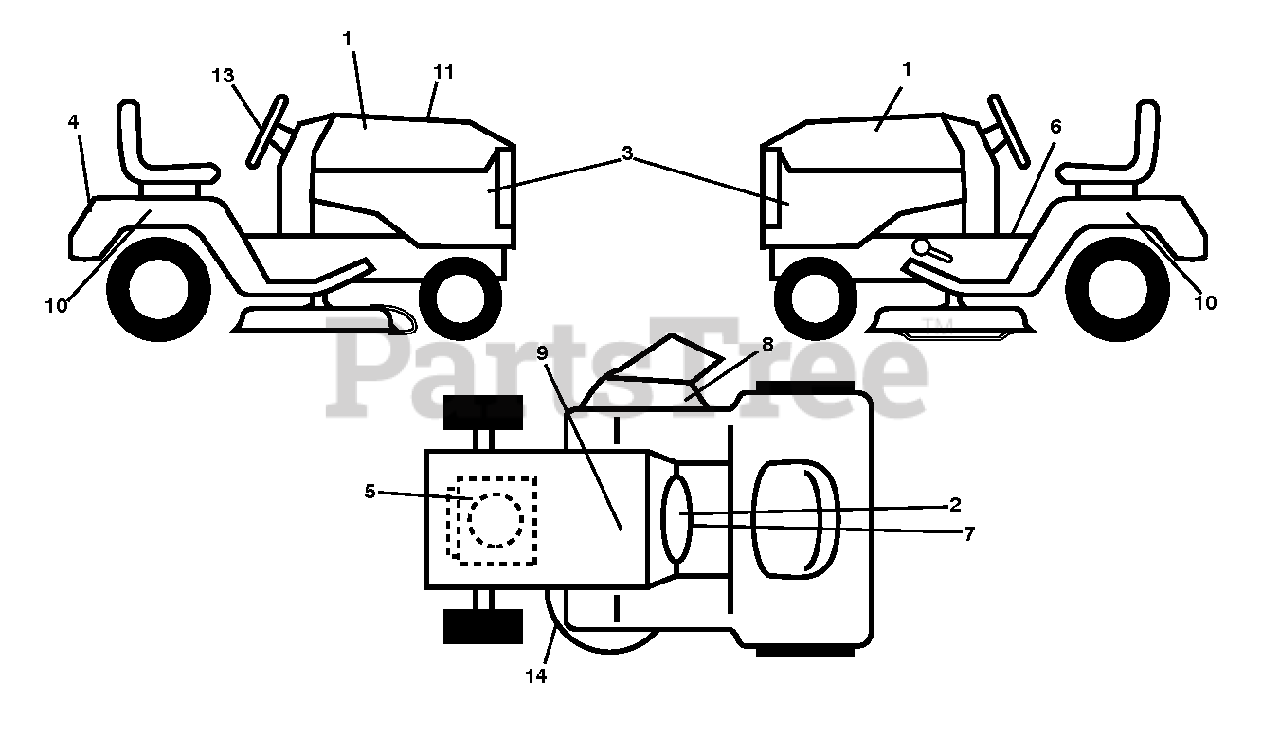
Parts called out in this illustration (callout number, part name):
1	DECAL.HOOD.POULAN.PRO.SET
2	DECAL, WARNING SPARK ARRESTOR
4	DECAL.REAR.FNDR.LOGO.POULAN.PR
5	Decal, Engine Hp
6	Fender Warning Decal, English
8	DECAL.WARN.KEEP.HAND.AWAY
9	DECAL BTRY SYMBOLS
13	DECAL.STEER.WHEEL.POULAN.PRO
14	DECAL V BELT SCHEMATIC
